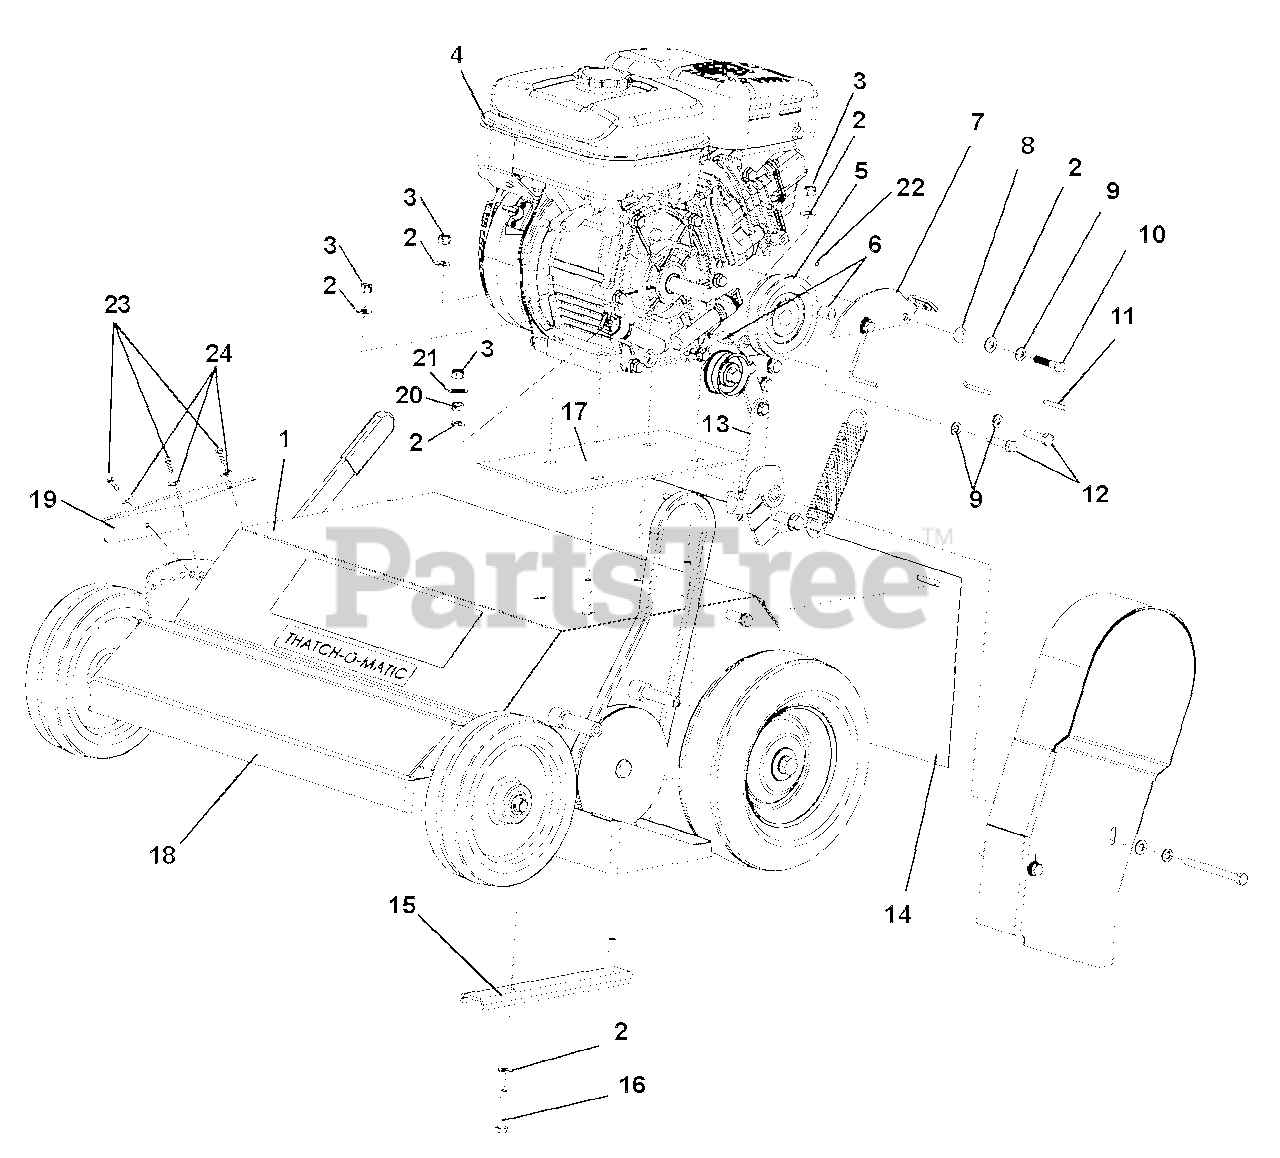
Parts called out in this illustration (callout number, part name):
1	Housing Weldment w/ Decals Gravely
2	Washer, Flat-Steel .344 x .688 x .065
3	Nut, Locking-Nylon 5/16-18
4	Engine, Subaru 6HP SP170
5	Pulley, 2275-3/4" Bore (Used with spring tine reel)
7	Weld-Bracket
8	Belt Finger
9	Washer, Locking .31 x .078 Regular
10	Bolt, Hex Head 5/16-24 x 1.5
11	3/16 Key 1 1/4"
12	Bolt HH 5/16-24 x 1.25
13	Clutch Pulley Assembly
14	Drag Strip
15	Stiffener
16	Bolt, Hex .31-18 x 1.75
17	Mounting Plate
18	Front Bumper Welment
19	Guard, Right Hand
20	Nut, Locking-Center-Jam .31-18
21	Washer, Lock Internal .31
22	Screw, Set .31-18 x .38 Socket Head
23	Bolt, Hex .25-20 x .75 Grade 5
24	Washer, Locking .25 x .062 Regular
P89-133B	Pulley-Sheave, AK-39 bore (Used with flail reel)
